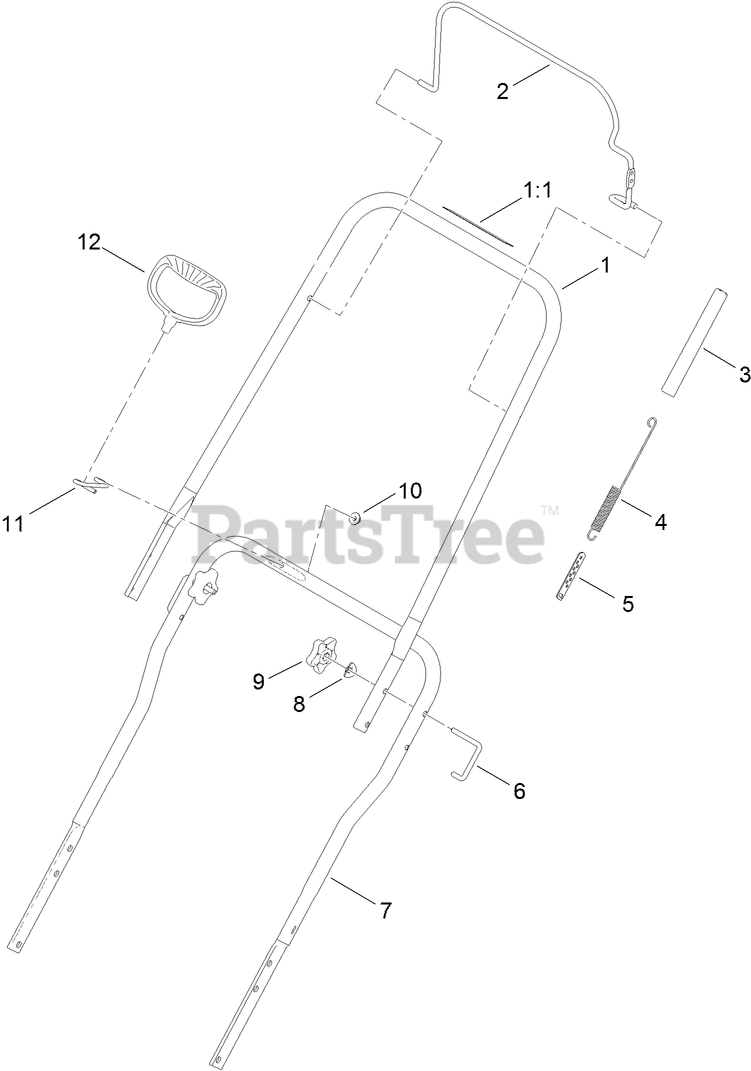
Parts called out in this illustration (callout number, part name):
1	UPPER HANDLE ASM
1:1	DECAL-DRIVE, ROTOR
2	BAIL-CLUTCH
3	COVER-SPRING
4	SPRING-EXTENSION, CLUTCH
7	HANDLE-LOWER
8	WASHER
9	KNOB-HANDLE
10	NUT-HF
11	GUIDE-ROPE
12	HANDLE-RECOIL
